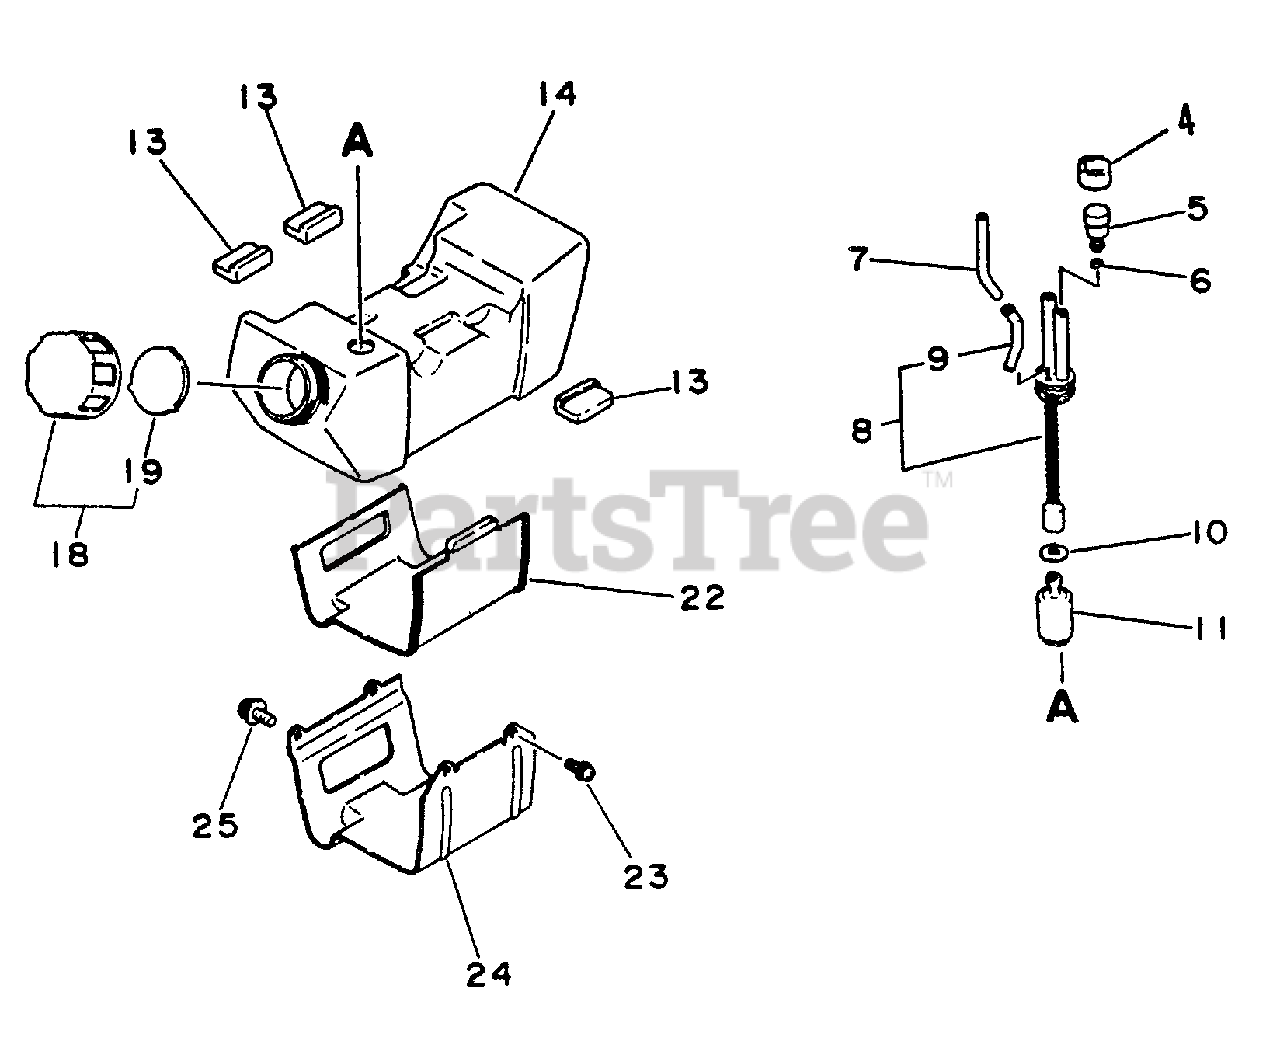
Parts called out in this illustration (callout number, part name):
4	COVER, VENT
5	VENT, FUEL TANK
6	CLIP - 5.5
7	PIPE - 3X6X50 -- CLEAR
8	FUEL SYSTEM KIT
9	CONNECTOR, PIPE
10	WASHER - 5
11	FILTER, FUEL
13	CUSHION, FUEL TANK
14	TANK, FUEL
18	CAP ASSY
19	GASKET, CAP
23	SCREW - 4X10
24	BRACKET, FUEL TANK
25	SCREW - 5X12
